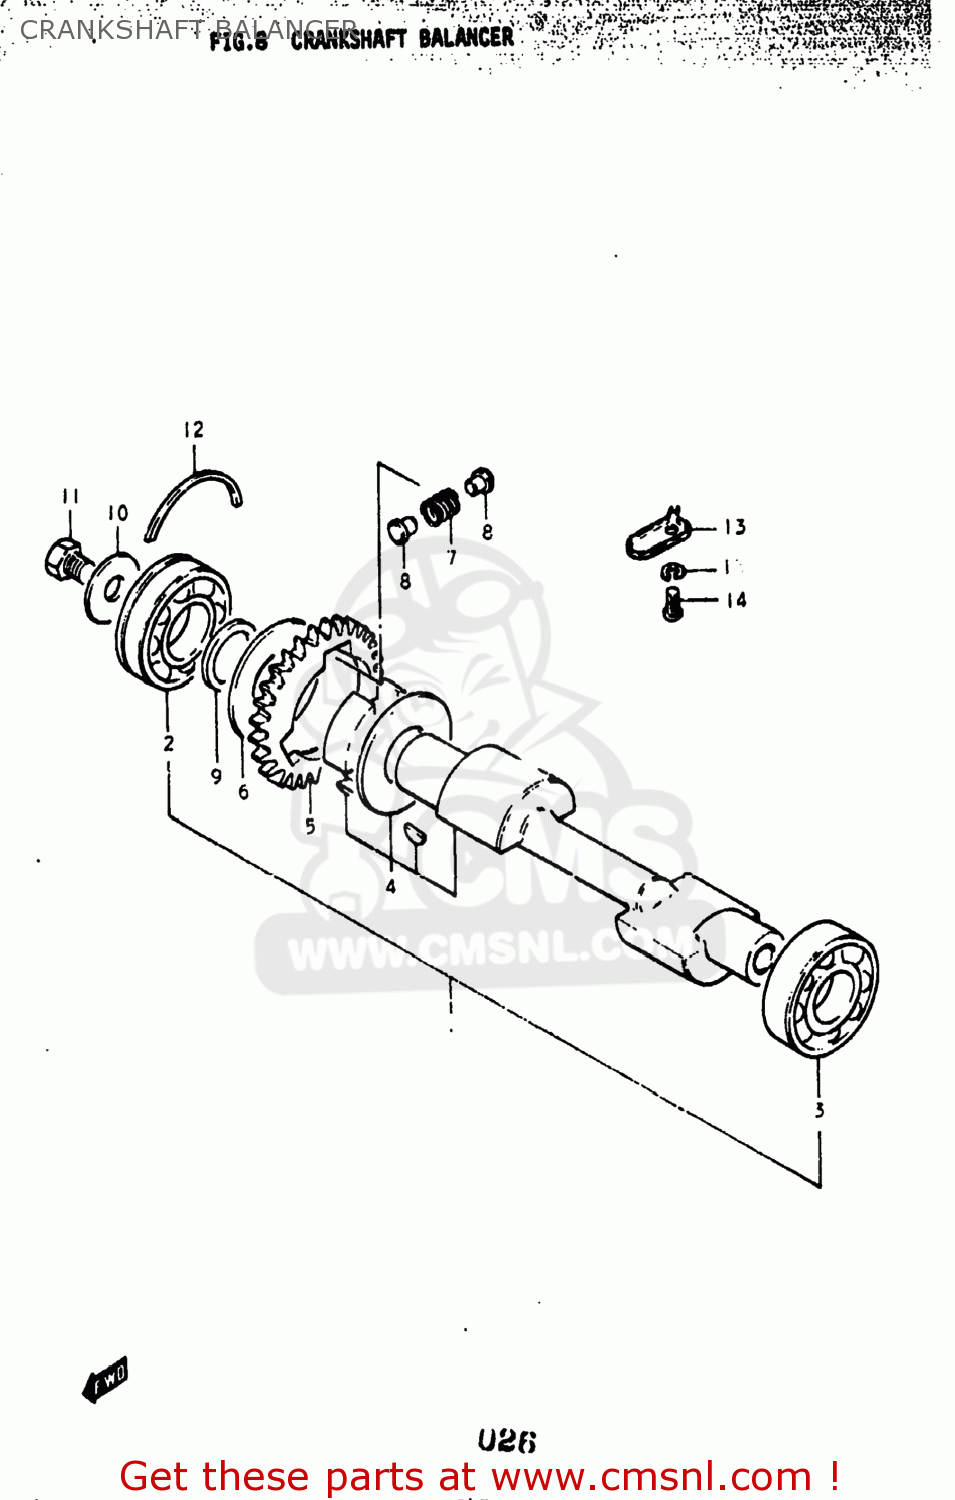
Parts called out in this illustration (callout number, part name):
1	BALANCER,CRANKSHAFT
2	BEARING
3	BEARING
4	CLUTCH SET,STARTER
5	GEAR,CRANK BALANCER DRIVE
6	WASHER (31X70X3)
7	SPRING
8	PIN
9	WASHER
10	WASHER
11	BOLT 12X16X1.25
12	C-RING
13	PLATE, OIL RESERVE
14	SCREW
15	LOCK WASHER
